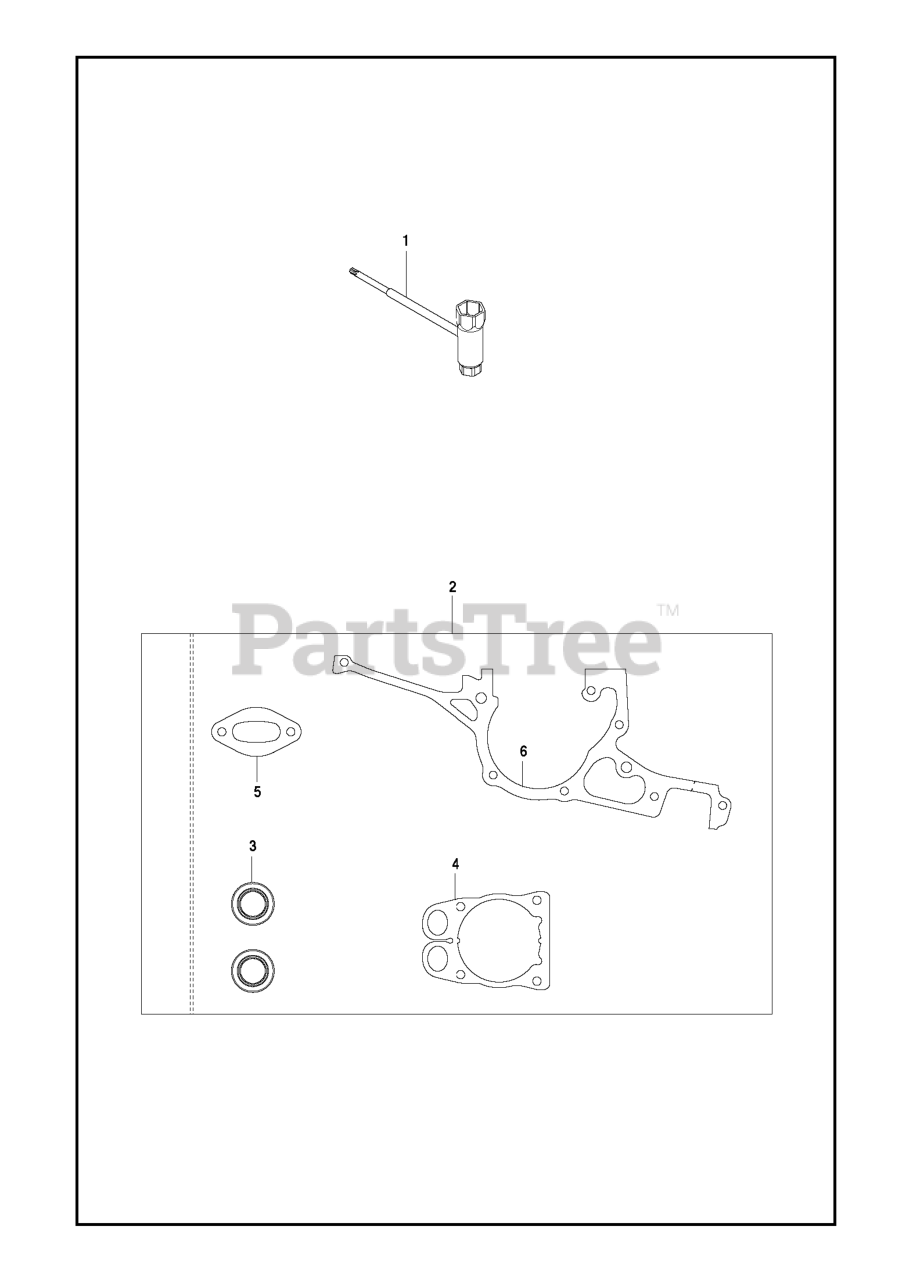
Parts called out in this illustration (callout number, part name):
2	GASKET KIT K960 K970/K970-II/K
3	SEALING RING
4	GASKET CYLINDER
6	GASKET CRANKCASE K970
